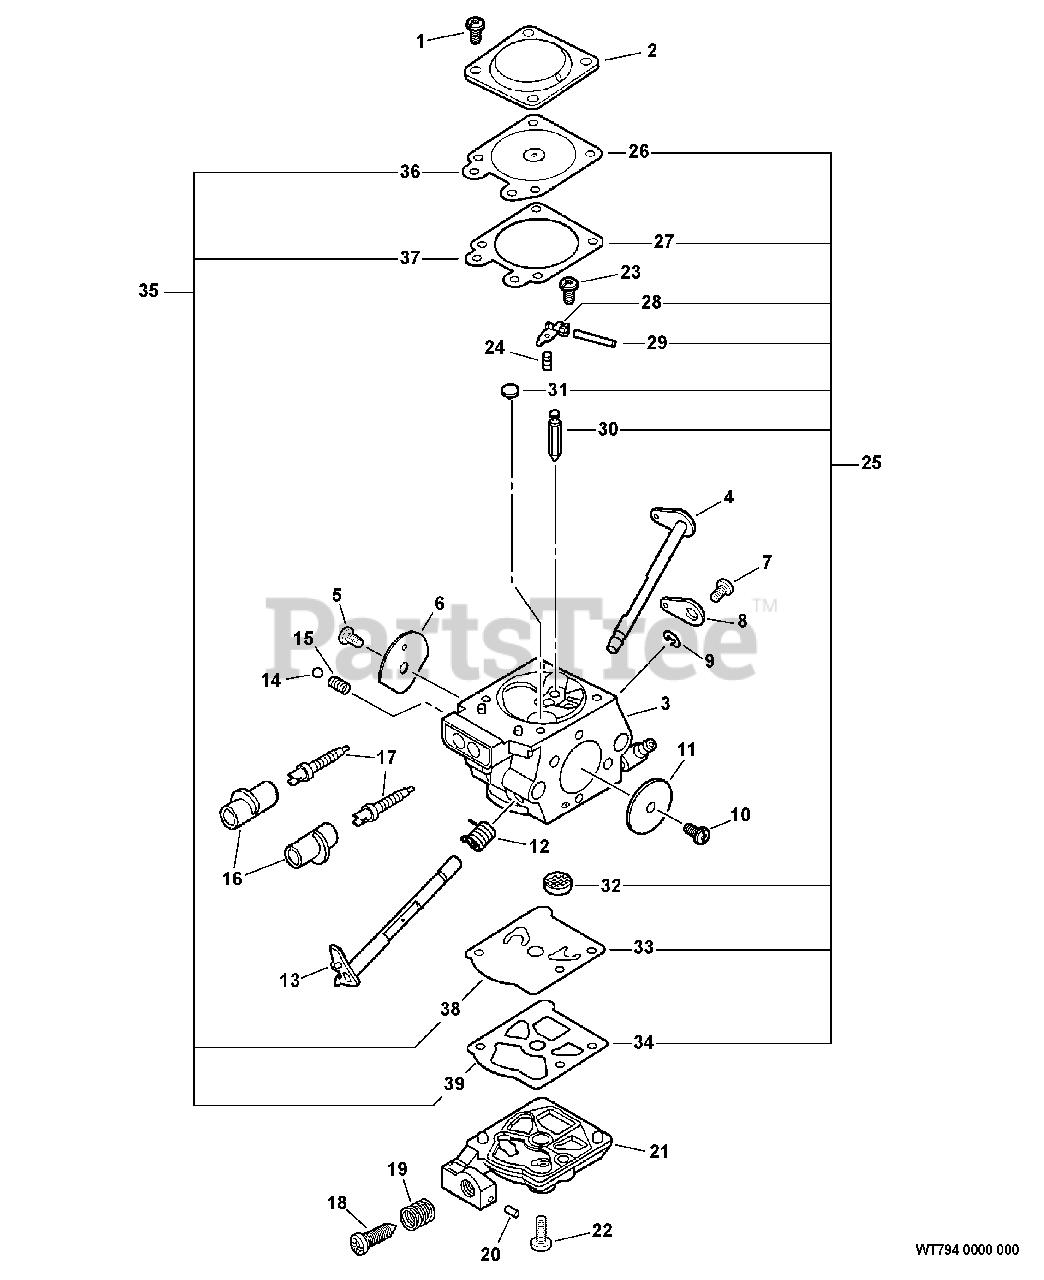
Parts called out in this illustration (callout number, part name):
2	COVER, METERING
3	BODY, CARBURETOR
4	SHAFT, CHOKE
6	VALVE, CHOKE
8	LEVER, THROTTLE
9	RING, RETAINING
11	VALVE, THROTTLE
12	SPRING, THROTTLE RETURN
13	SHAFT, THROTTLE
15	BALL, CHOKE
16	CAP, LIMITER
17	NEEDLE - MIXTURE
18	SCREW, IDLE ADJUST
19	SPRING, IDLE ADJUST
21	COVER, PUMP
22	SCREW, PUMP COVER
23	SCREW, METERING LEVER PIN
24	SPRING, METERING LEVER
25	REPAIR KIT
26	DIAPHRAGM, METERING
27	GASKET, DIAPHRAGM
28	LEVER, METERING
29	PIN, METERING LEVER
30	VALVE, INLET NEEDLE
31	PLUG, WELCH
32	STRAINER
33	DIAPHRAGM, PUMP
34	GASKET, PUMP
35	DIAPHRAGM/GASKET KIT
36	DIAPHRAGM, METERING
37	GASKET, DIAPHRAGM
38	DIAPHRAGM, PUMP
39	GASKET, PUMP
